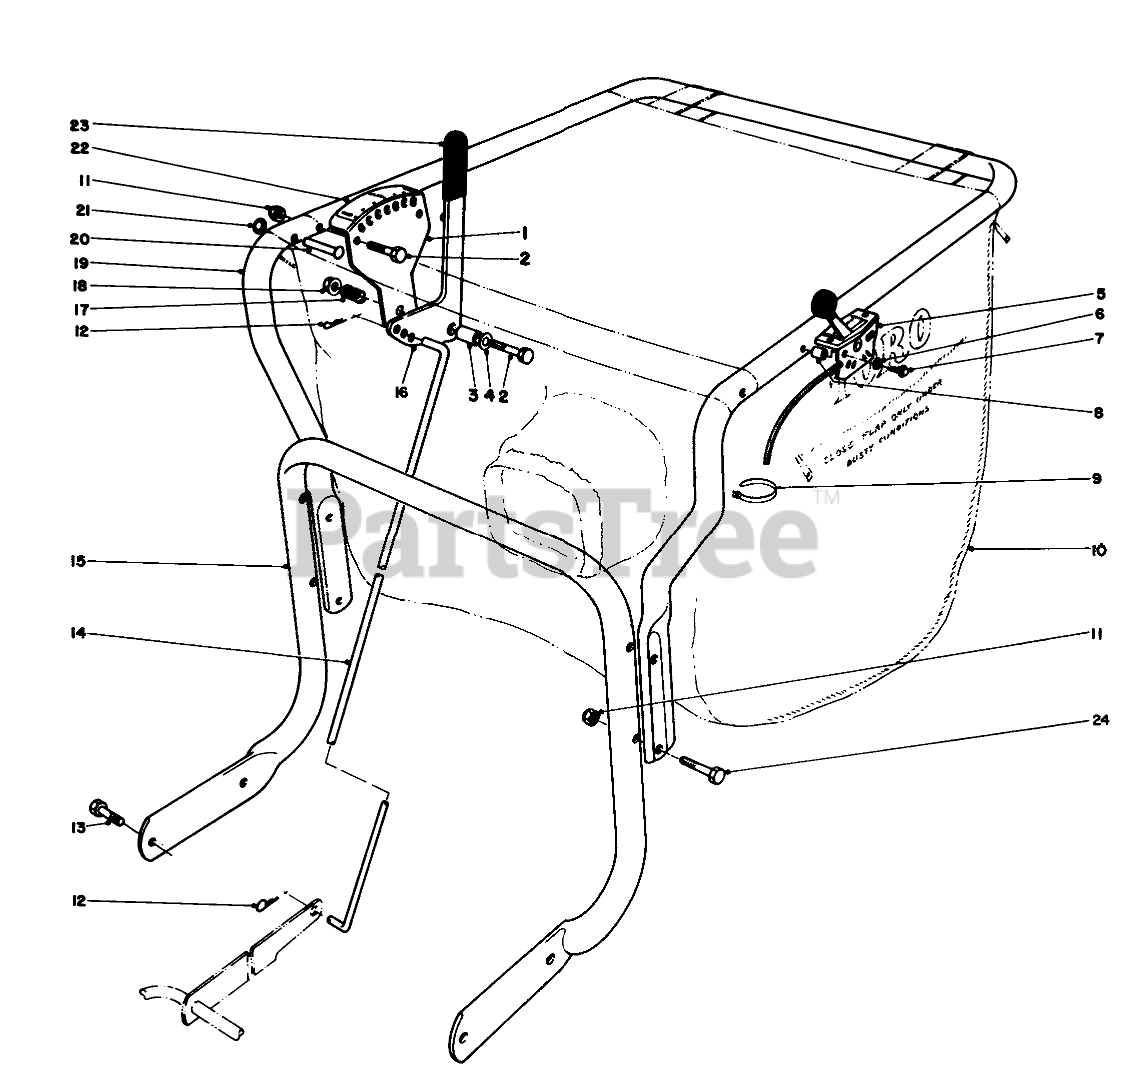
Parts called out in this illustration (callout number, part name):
1	Adjustment Bracket
2	SCREW-HH
3	SPACER
4	WASHER-FLAT
5	THROTTLE CONTROL
6	WASHER-LOCK, EXT
7	10-24 X 1 PAN HD SCR
8	SPACER
9	TIE-CABLE
10	VACUUM BAG
11	NUT-LOCK, NI
12	PIN-COTTER
13	SCREW-HH
14	HEIGHT ADJ. ROD
15	HANDLE
16	Handle-Adjustment
17	SPRING-COMPRESSION
18	NUT-HF
19	HANDLE-UPPER, VACUUM
20	RIVET
21	NUT-PUSH IN
22	HT ADJ DECAL
23	GRIP-HANDLE
24	SCREW-HH
